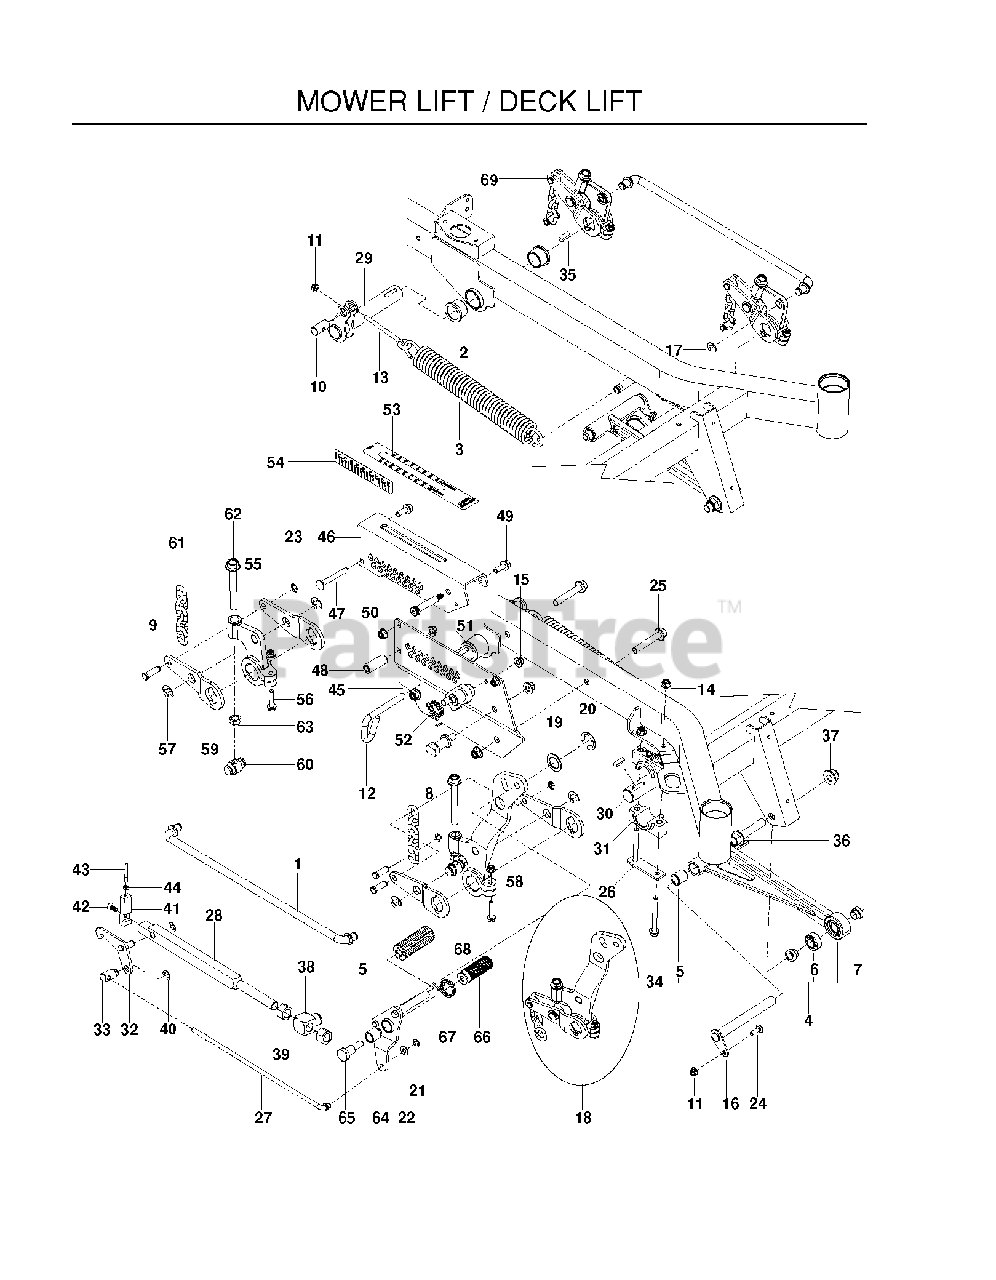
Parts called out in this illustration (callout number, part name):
2	BUSHING, FLANGE 1.25 X 1.0
3	SPRING, EXTENSION
4	ASSEMBLY, STRUT
5	BUSHING, SLEEVE 3/4 X 1.0
6	BALL JOINT, 3/4" SWIVEL
7	SPACER, STRUT
8	GUIDE, HEIGHT BAR
9	PIN, 7/16 CLEVIS
10	PIVOT, SPRING
11	5/16-18 NYLOC FLANGE NUT
12	PIN, HEIGHT
13	EYE BOLT 4.5`
14	NUT 3/8-16 HEX FLG NYLOC ZD
15	NUT, 1/2-13 HEX FLG NYLOC ZD
16	PIN, STRUT
17	E-RING 5/8
18	ASSEMBLY, DECK LIFT LEVER
19	MACHINE BUSHING
20	E-RING 1"
21	E RING 3/8"
22	WASHER 3/8 SAE FLAT
23	RING, E, 7/16
24	RHSNB 5/16C X 1
25	HFFS 1/2-13 X 3 GD 5 ZD
26	PLATE, PILLOW BLACK
27	ROD, HEIGHT LATCH
28	BAR, HEIGHT
29	SHAFT, RR LIFT
30	SHAFT, LIFT, FT
31	BLOCK, PILLOW
32	LATCH, HEIGHT WLDMT
33	SWIVEL, HEIGHT LATCH
34	HHFS 3/8-16 X 3.5 GD 5 ZD
35	KEY, 5/16 SQ X 1.0
36	HHFS 5/8-11 X 3.0 GD 8 ZD
37	NUT 5/8-11 FLG NYLOC ZD
38	SWIVEL, HEIGHT BAR
39	NUT 3/4-10 HEX ZD
40	E-RING 1/2 (2 2)
41	CAP, HEIGHT BAR
42	SCREW, 5/16-18 X 3/4 FLAT HEX
43	LINK, INDICATOR
44	NUT 1/4-20 JAM
45	PLATE, INNER HEIGHT, ORANGE
46	PLATE, OUTER HEIGHT ORG
47	3/8-16 X 3` CARR BOLT
48	SPACER, HEIGHT PLATE
49	HHFS 3/8-16 X 1 GRD 5 ZD
50	BOLT, SHOULDER, 1/2 X 2.25
51	LATCH, TRANSPORT WLDMT
52	SPRING, TORSION
53	DECAL, HEIGHT CE
54	DECAL, HEIGHT CE
55	ARM, CAST LIFT
56	HHFS 5/16-18 X 1.5 GD 5
57	E RING 3/4
58	ARM, LIFT LEVER
59	ARM LIFT BLK
60	SHAFT, LIFT TRUNION WSL
61	LIFT CHAIN
62	HHFS 1/2-13 X 4 GR 5
63	NUT 1/2 HEX JAM
64	PEDAL, RELEASE WLDMT
65	BOLT, SHOULDER
66	PAD, FOOT PEDAL
67	SPRING, TORSION
68	PEDAL, DECK HEIGHT
69	ASSEMBLY, DECK LIFT CRANK
